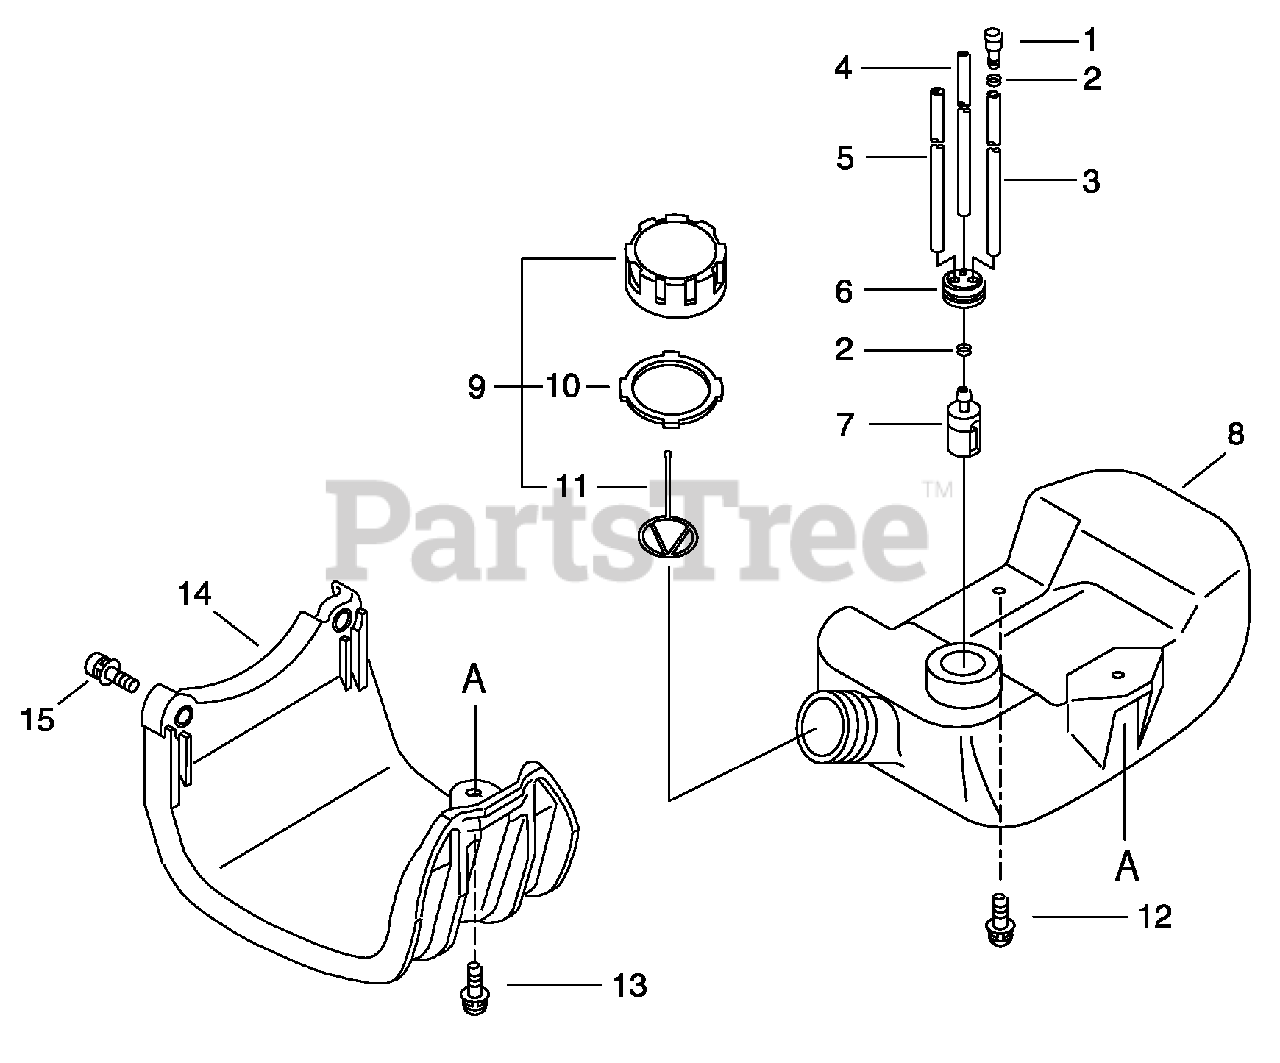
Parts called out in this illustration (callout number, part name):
1	VENT, FUEL TANK
2	CLIP - 6.5
3	PIPE - 3X6X100 -- BLACK
4	PIPE - 3X6X170 -- BLACK
5	PIPE - 3X6X60 -- CLEAR
6	GROMMET
7	FILTER, FUEL
8	TANK, FUEL
9	CAP ASSY - ORANGE
10	GASKET, CAP
11	CONNECTOR, CAP
12	SCREW - 5X16
13	SCREW - 5X20
14	GUARD, FUEL TANK
15	SCREW - 5X22
